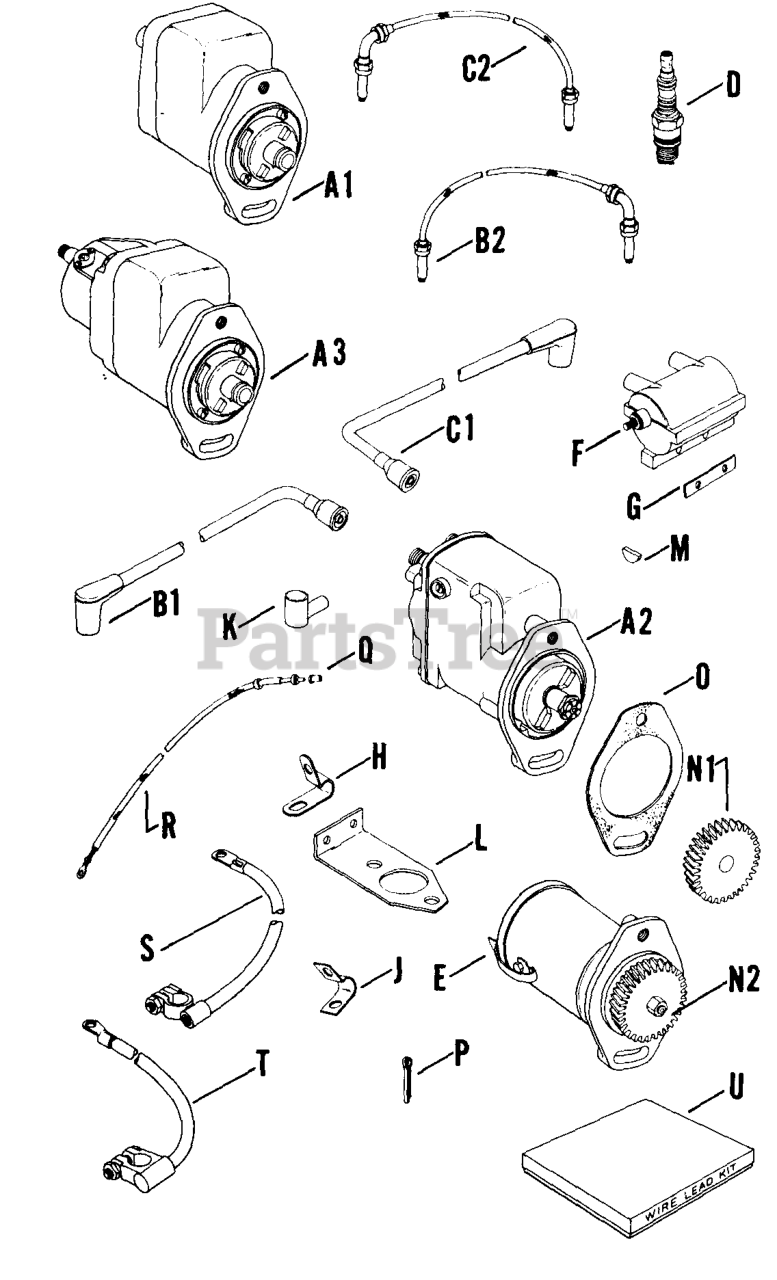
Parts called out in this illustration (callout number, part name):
A1	MAGNETO - USE A-270966
B1	KIT - USE 238057
C1	KIT - USE 238057
D	SPARK PLUG - USE 41 132 06
O	GASKET - DISCONTINUED
